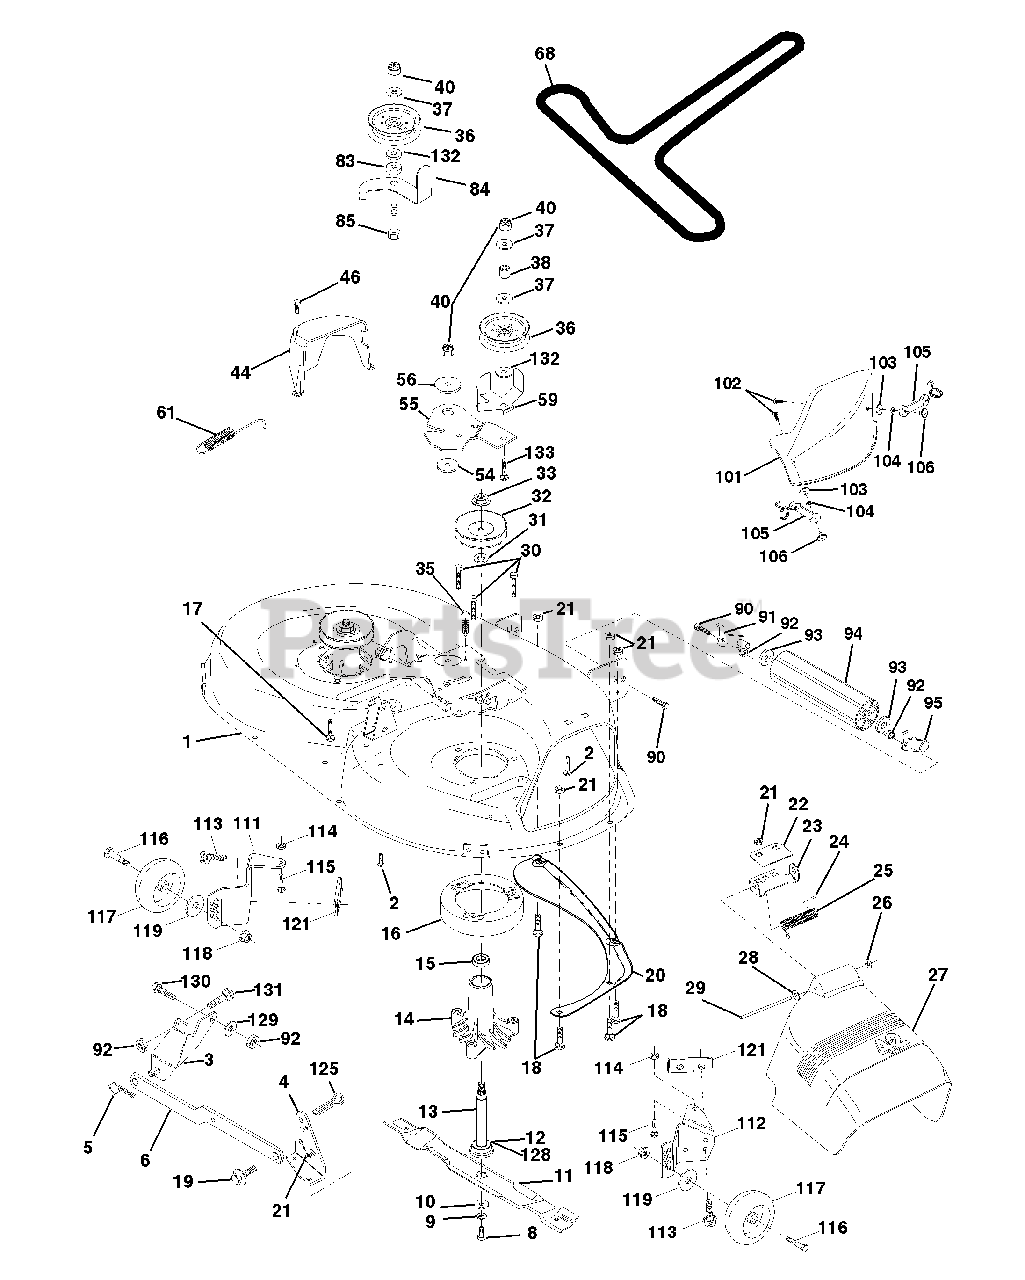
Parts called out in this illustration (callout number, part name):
1	Housing Asm Mower 42" 94 T-Path
2	Bolt Rdhd Sqnk 5/16-18unc X 3/4
3	Bracket Asm Fr Sway Bar 38/42
4	Bracket Asm Deck 42" sway Bar
5	Retainer Spring
6	Arm Suspension Rear
8	Bolt 3/8-24 x 1 25 Gr8 Patched
9	Washer Lock Hvy 3/8 Unplated
10	Washer Hard Blade Mower Vented
11	Blade Mower Mulching 42"
12	Bearing Ball #6204 (Mandrel)
13	Shaft Asm W/lower Bearing
14	Housing Mandrel Vented(machd)
15	Bearing Ball Mandrel
16	Stripper Round Mower
17	Bolt Rdhd Sqnk 3/8-16 X 2-1/4
18	Bolt Carr 5/16-18 X 5/8
19	Bolt Shoulder
20	Baffle Vortex 42
21	Nut Crown Lock 5/16-18
22	Stiffener Bracket 42" deck
23	Bracket Deflector Mower 42"
24	Cap Sleeve 80 x 112 Blk Mower
25	Spring Torsion Deflector 2 52
26	Nut Push Phos & Oil
27	Shield Deflector Mower 42" Blk
28	Washer 11/32 X 5/8 X 16 Ga
29	Rod Hinge 42" 6 75 Wlg
30	Screw Thdrol Washer Head
31	Washer Spacer Mower Vented
32	Pulley Mandrel 42"
33	Nut 9/16 top Lock Flng Cntr
35	Fastner Christmas Tree
36	Pulley Idler Flat 3 060
37	Washer 13/32 X 13/16 X 16 Ga
38	Spacer Spring Stop Idler
40	Nut Lock 3/8-16 Unc
44	Guard Mandrel LH Black
46	Screw Thdrol 1/4-20x5/8
54	Washer Hardened
55	Arm Idler 42" mower LT/YT
56	Spacer Retainer Pm Mower
59	Guard, Belt
61	Spring Ext. Elect
68	V-Belt Mower
83	Washer Sintered
84	Keeper Belt Idler
85	Bolt Carriage 3/8-16 x 2-1/4 Gr.5
90	Bolt Fin Hex 3/8-16unc X 1
91	Bracket Asm Noseroller LH
92	Nut Lock Hex w/ins. 3/8-16 UNC
93	Washer 17/32 X 7/8 X 16 Ga
94	Roller Nose 38 & 42
95	Bracket Asm Noseroller RH
101	Cover Mulching 42" Blk
102	Screw
103	Washer #10
104	Washer Lock #10
105	Latch Asm Bagger
106	Nut Weld .327/.304 #10-24
111	Bracket Wheel Gauge Lh 42" Deck
112	Bracket Gauge Wheel Rh 42" Deck
113	Screw Thdrol 5/16-18 x 3/4 TYT
114	Nut Keps 5/16 - 18 UNC
115	Bolt Carriage 5/16 - Unc x 1/2
116	Bolt Shld
117	Wheel Gauge Donut
118	Nut Centerlock 3/8 - 16 UNC
119	Washer 3/8 x 7/8 x 14 Ga.
125	Cotter Pin
128	Washer Felt
129	Washer 13/32 x 13/16 x 12 Ga.
130	Bolt Fin Hex 3/8-16unc x 1 Gr. 5
131	Bolt Rdhd Sqnk 3/8-16 UNC
132	Washer 13/32 x 1-3/8 x 3 Ga.
133	Bolt RDHD 3/8-16 UNC x 2-3/4 Gr.5
